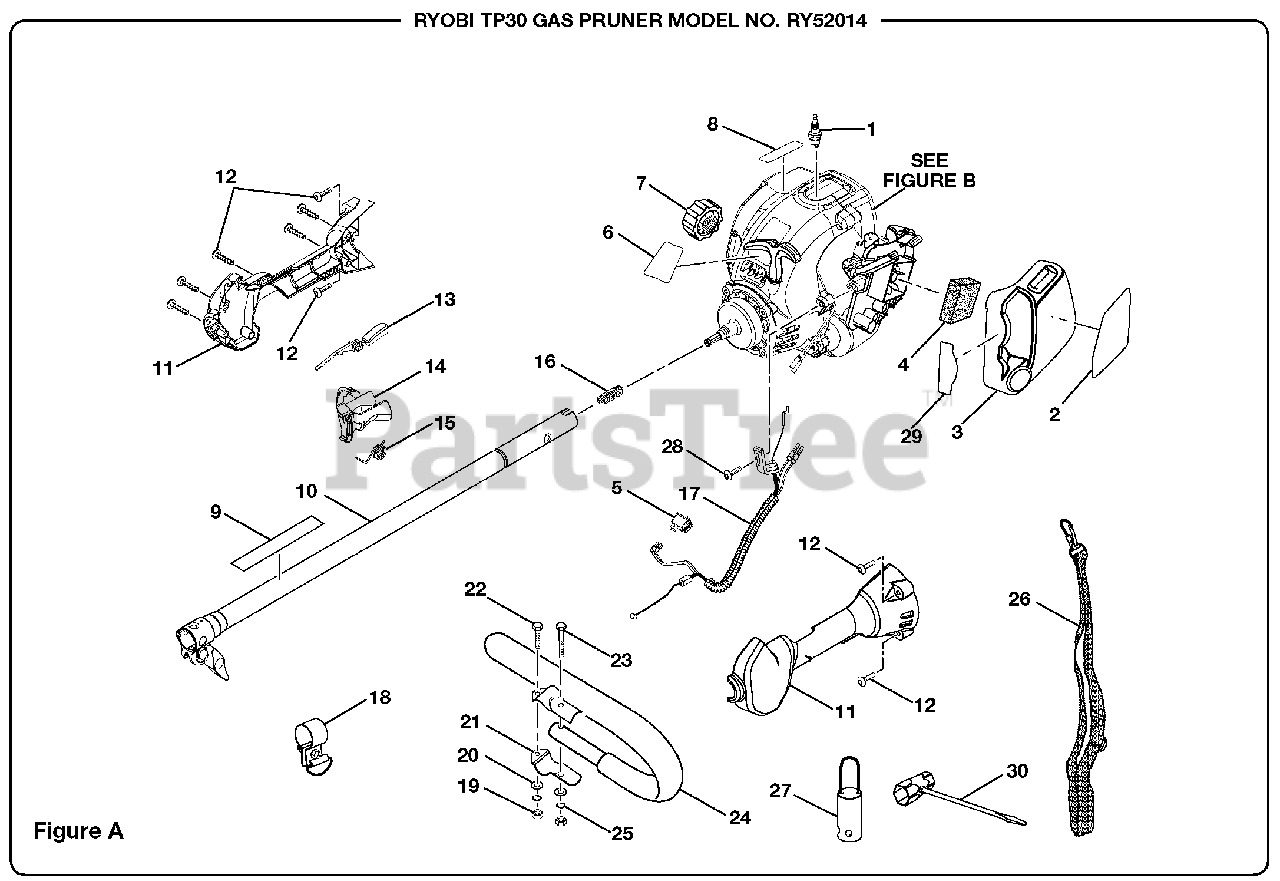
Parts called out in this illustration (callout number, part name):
1	Spark Plug (Champion RCJ4)
2	Starting Label
3	Air Box Cover
4	Air Filter Element
5	Switch (Momentary Contact)
6	Model Label (TP30)
7	Fuel Cap Assembly
8	Logo Plate
9	Warning Decal (TP30)
10	Upper Boom Assembly (TP30)
11	Control Handle Assembly
12	Screw (10-14 X 1 In.)
13	Trigger Lock
14	Trigger
15	Torsion Spring
16	Compression Spring
17	Throttle And Lead Assembly
18	Strap Hanger (TP30)
19	Hex Nut (1/4-20)
21	Handle Bar Clamp
22	Bolt (1/4-20 X 1 In. Hex Hd.)
23	Bolt (1/4-20 X 1-1/2 In. Hex Hd.)
24	"J" Handle And Grip
25	Lock Washer
26	Shoulder Strap
27	Hanger Cap
28	Screw (10-24 X 7/8 In.)
29	Choke Label
30	Combination Wrench
